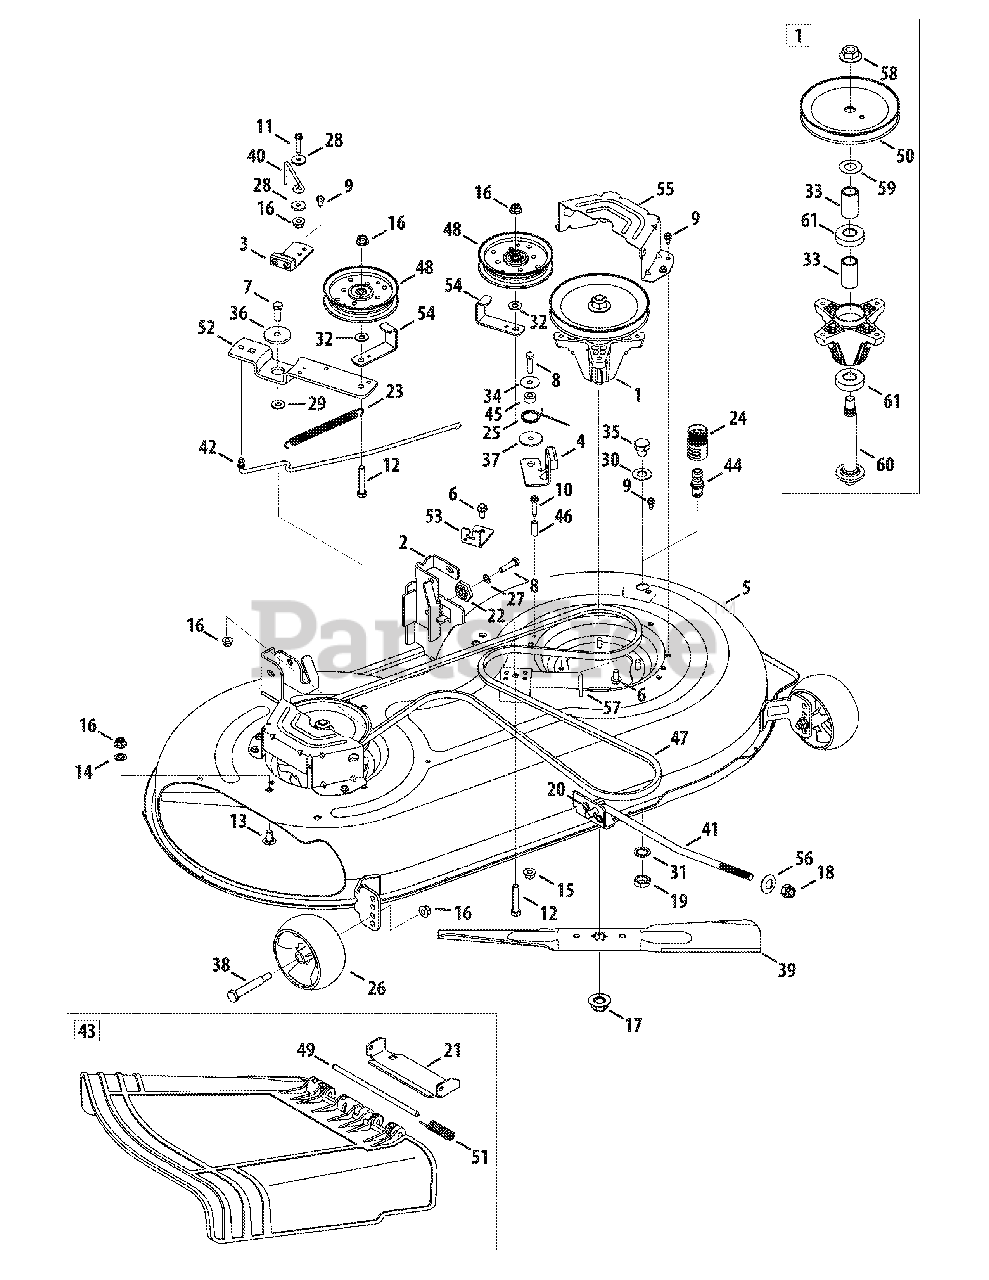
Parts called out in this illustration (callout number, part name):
1	Pulley Spindle Ass’y 6.3 dia.
2	Deck Hanger Bracket Ass'y LH
3	Deck Brake Assembly
4	Deck Brake Assembly
5	Deck Assembly, 42" w/ deck wheels
6	S-Tapp Scr 5/16-18 x .75
7	Hex. Hd. Cap Scr. 3/8-16 x 1.0 Gr. 5
8	Hex Wash Tap Scr 5/16-18 x 1.25
9	Hex Wash S-Tapp Scr 1/4-20 x .50
10	Hex Wash HD Bolt 1/4-20 x 1.50" Lg.
11	Hex Bolt 1/4-20 x 1.25
12	Hex. Hd. Cap Scr. 3/8-16 x 2.0 Gr. 5
13	Carriage Bolt 3/8-16 x .75 Gr. 1
14	Push Nut, 3/8
15	Hex Flange Locknut 5/16-18 Gr. F, Nylon
16	Hex Flange Locknut 3/8-16 Gr. F Nylon
17	Hex Flange Locknut 5/8-18
18	Hex Locknut 1/2-13
19	Hex Nut M16-1.5 DIN 936
20	Bow Tie Cotter Pin
21	Chute Bracket
22	Deck Gear Adjuster
23	Extension Spring .62 dia. x 6.12 Lg.
24	Water Nozzle Adapter
25	Torsion Spring .992 ID x 1.17 OD
26	Deck Wheel 5.0 Dia.
27	L-Wash 5/16 ID
28	Flat Washer .265 ID x .938 OD x .120
29	Flat Washer .385 ID x 1.0 OD x .030
30	Flat Washer .640 ID x 1.24 OD x .06
31	L-Washer Internal
32	Flat Washer .385 ID x .870 OD x .092
33	Spacer .792 x 1.060 x 1.860
34	Flat Washer .330 ID x 1.25 OD x .06
35	Screw Plug M16 x 1.50
36	Shoulder Spacer .8540 x .200
37	Shoulder Spacer .50 Dia x .1475
38	Shoulder Bolt .496 x 2.5, 3/8-16
39	Blade, 21.23", 2-in-1
40	Belt Keeper Rod
41	Front Lift Deck Rod
42	Brake Control Rod
43	Side Discharge Chute Assembly
44	Deck Water Nozzle
45	Spacer .315 x .750 x .375" Lg.
46	Spacer .260 x .375 x 1.030 Lg.
47	V-Belt
48	Idler Pulley w/Flange 4.25 Dia
49	Hinge Pin .3125 diam. x 7.96" Lg.
50	Deck Pulley 6.3 dia.
51	Torsion Spring .44 ID x 2.0
52	Idler Pivot Bracket
53	Deck Cable Engagement Bracket
54	Belt Guard Pulley Bracket
56	Deck Lift Pivot Cup
57	Deck Support Stationary Idler Brkt.
58	Hex Flange Locknut 5/8-18
59	Flat Washer .760 ID x 1.5 OD
60	Spindle Shaft 6.11" Lg.
61	Ball Bearing .787 ID x 1.85 OD x .551
